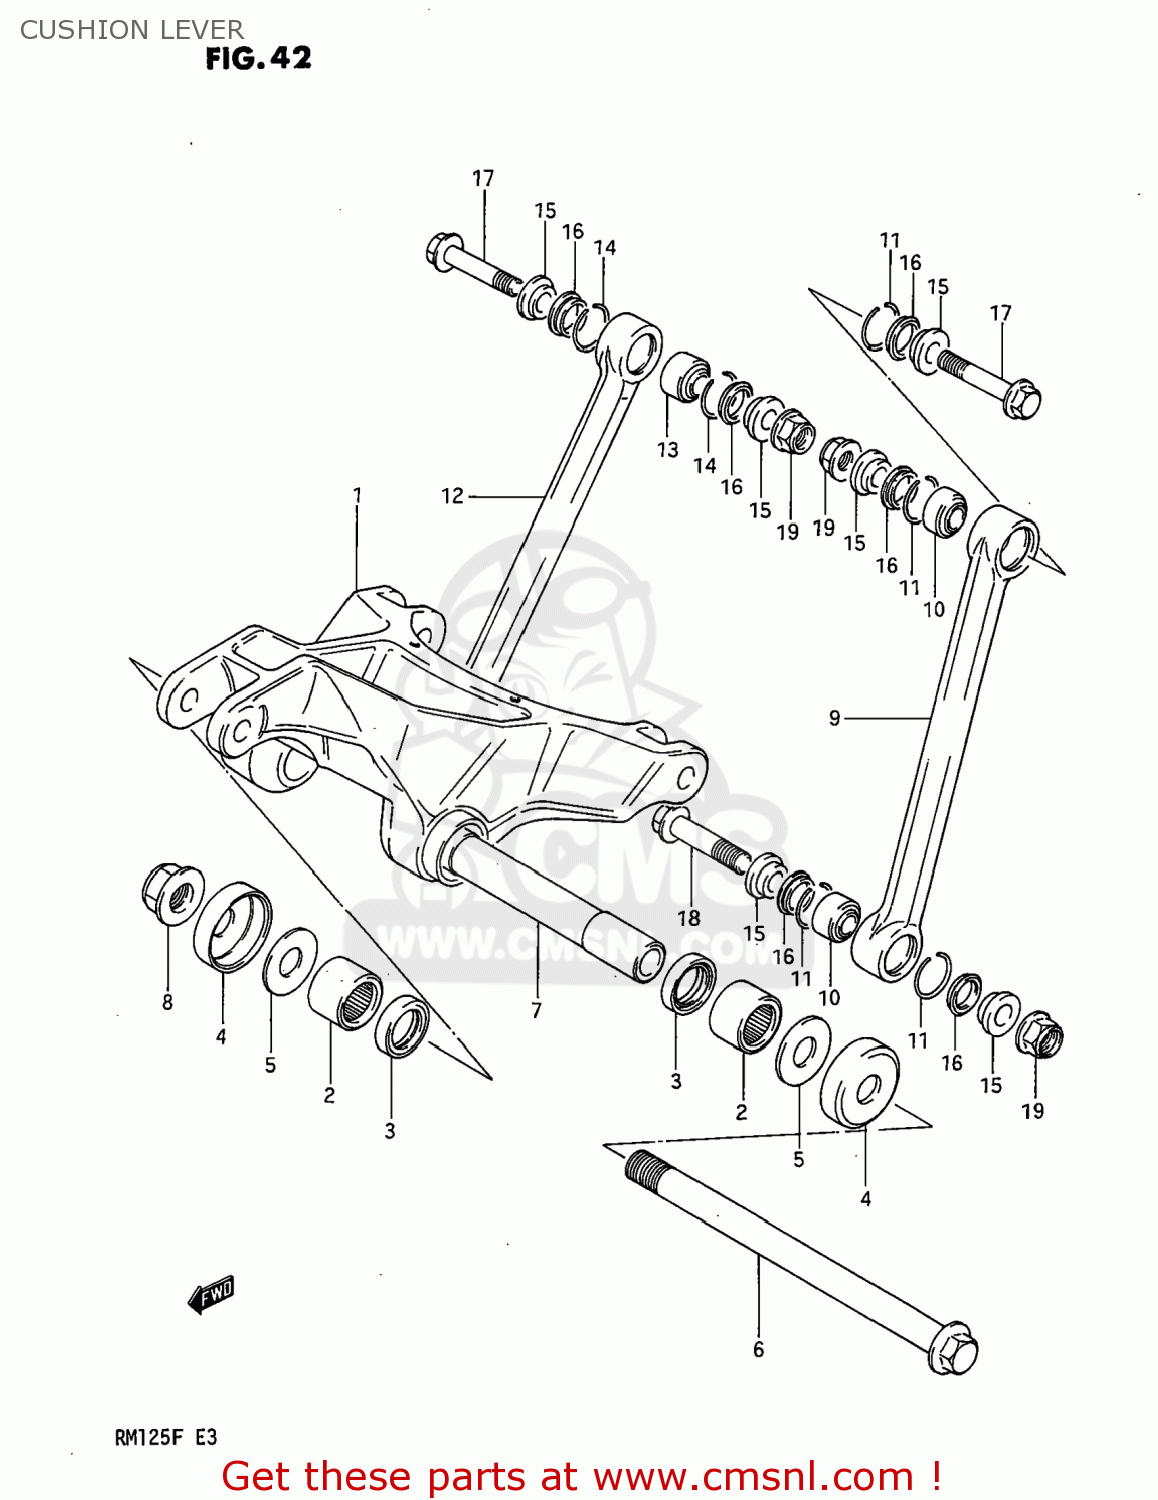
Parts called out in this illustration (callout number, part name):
1	LEVER SET,REAR CUSHION
2	BEARING(20X27X25)
3	SEAL,CUSHION LEVER DUST
4	CVR,RR SWGARM DUST SEAL(OD:40)
5	WASHER
6	SHAFT,REAR CUSHION LEVER
7	SPACER,REAR CUSHION LEVER
8	NUT
9	ROD SET,REAR CUSHION,LEFT
10	BEARING(10X21X13)
11	RING,BEARING STOPPER
12	ROD SET,REAR CUSHION,RIGHT
13	BEARING(10X21X13)
14	RING,BEARING STOPPER
15	SPACER,REAR CUSHION ROD
16	DUST SEAL,RR CUSHION ROD
17	BOLT,RR CUSHION ROD UPR
18	BOLT,RR CUSHION ROD LWR
19	NUT
